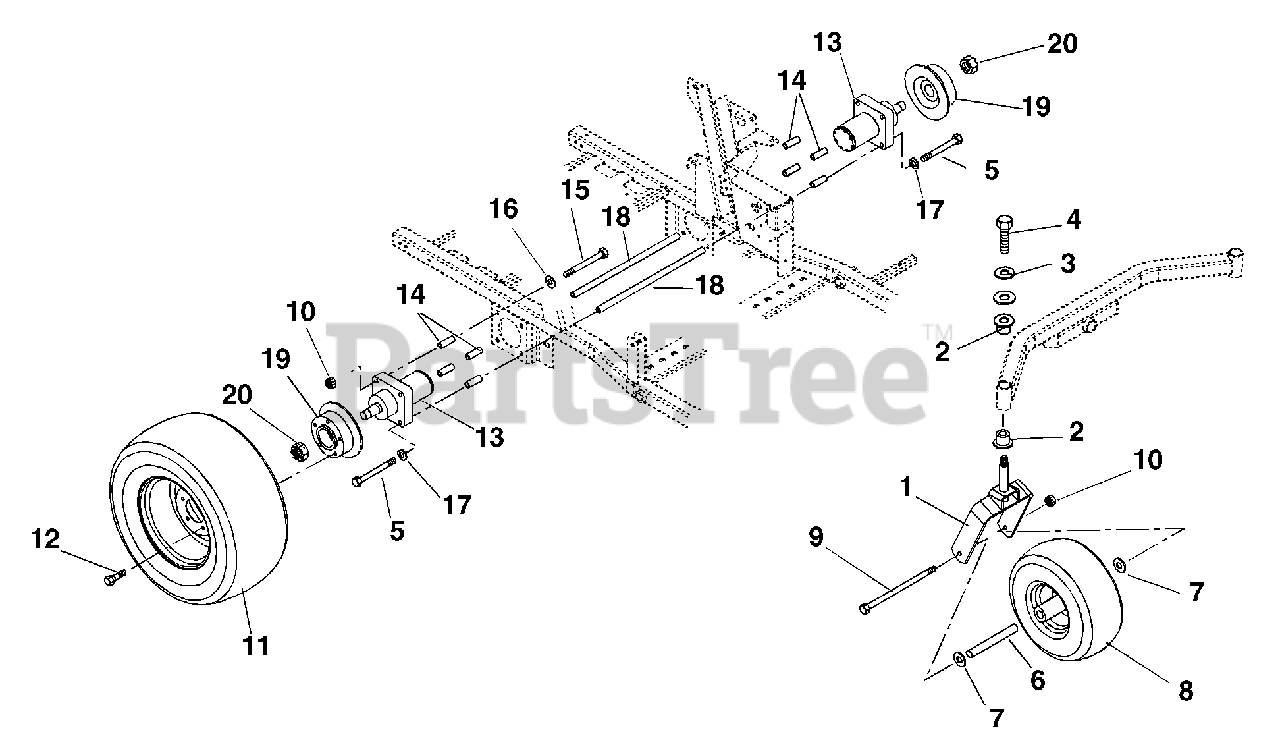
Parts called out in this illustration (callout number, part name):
1	Fork-Front
2	Bushing, Flange 1.020 x 1.385 x .75 x 1.75
3	Washer-Flat-Steel .380 x 1.50 x .125
4	Washer-Locking .38 x .094
5	Bolt-Hex .38-16X1.25 Grade 5
6	Spacer-Wheel
7	Washer-Flat-Steel .515 x 1.625 x .250
8	Wheel/Tire Assembly
8	Tire, 15 x 6-6
9	Bolt-Hex .50-13 x 9.00 Grade 5
10	Nut-Locking-Center .50-13
11	Wheel-Tire 23 x 8.50 Multi-Trac
11	Tire 23 x 8.50-12 Multitrac C/S
12	Bolt-Lug .50-20 x 1.62
13	Hydraulic Wheel Motor
14	Bushing-Sleeve .513 x .748 x 2.129
15	Bolt-Hex .50-13 x 5.00 Grade 8
16	Spacer .500 x .750 x .321
17	Washer-Locking .50 x .125
18	Rod-Motor Connecting
19	Hub and Disc
20	Nut -Lock Jam Patch
